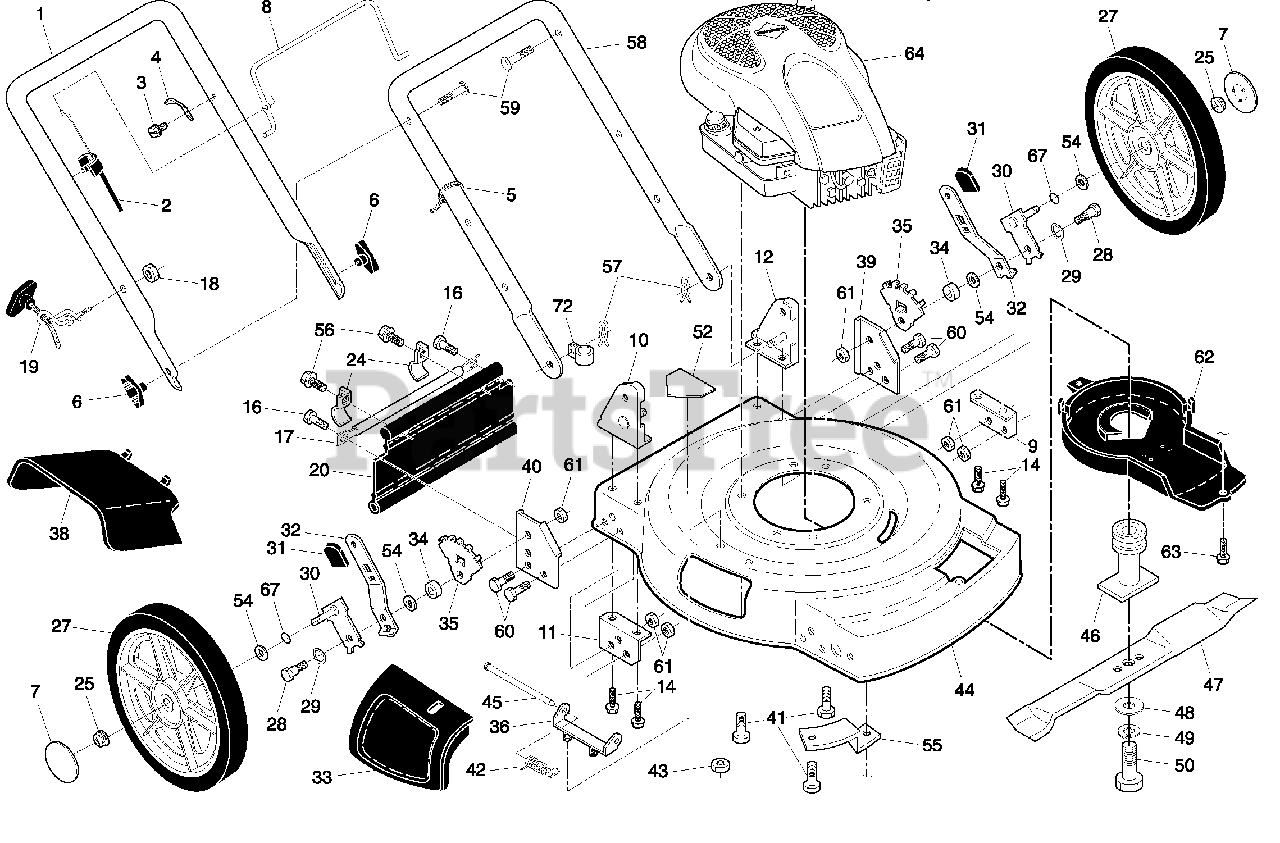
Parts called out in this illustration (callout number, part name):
1	Drive Control Cable Assembly
2	Bearing, Wheel Adjuster
3	Pan Head Tapping Screw #10-24 x 2-3/4
6	Spring Retainer
7	Control Bar, Drive
8	Hubcap
9	Locknut, Hex
11	Wheel & Tire Assembly
12	E-Ring
13	Pinion
14	Dust Cover
15	Pawl, Drive
16	Washer
18	Selector Knob
28	Drive Cover
35	Kit, Wheel Adjuster, LH
36	Gear Case Assembly, Complete
38	Locknut, Hex 1/4-20
40	Spring
41	Kit, Wheel Adjuster, RH
60	Case, Lower
61	Case, Upper
62	Gear, 27 Teeth
63	Lever, Clutch
64	Spring, Return
65	Shaft, Input
66	Dog, Movable
67	Dog, Fixed
68	Wire, Formed
69	Bearing, Ball
70	Fork, Shift
71	Seal, Output Shaft
72	Washer
73	Seal, Case
74	Bushing
75	Shaft, Output
76	Screw
77	Seal, Input Shaft
78	Pulley, Drive
79	Locknut, Hex
